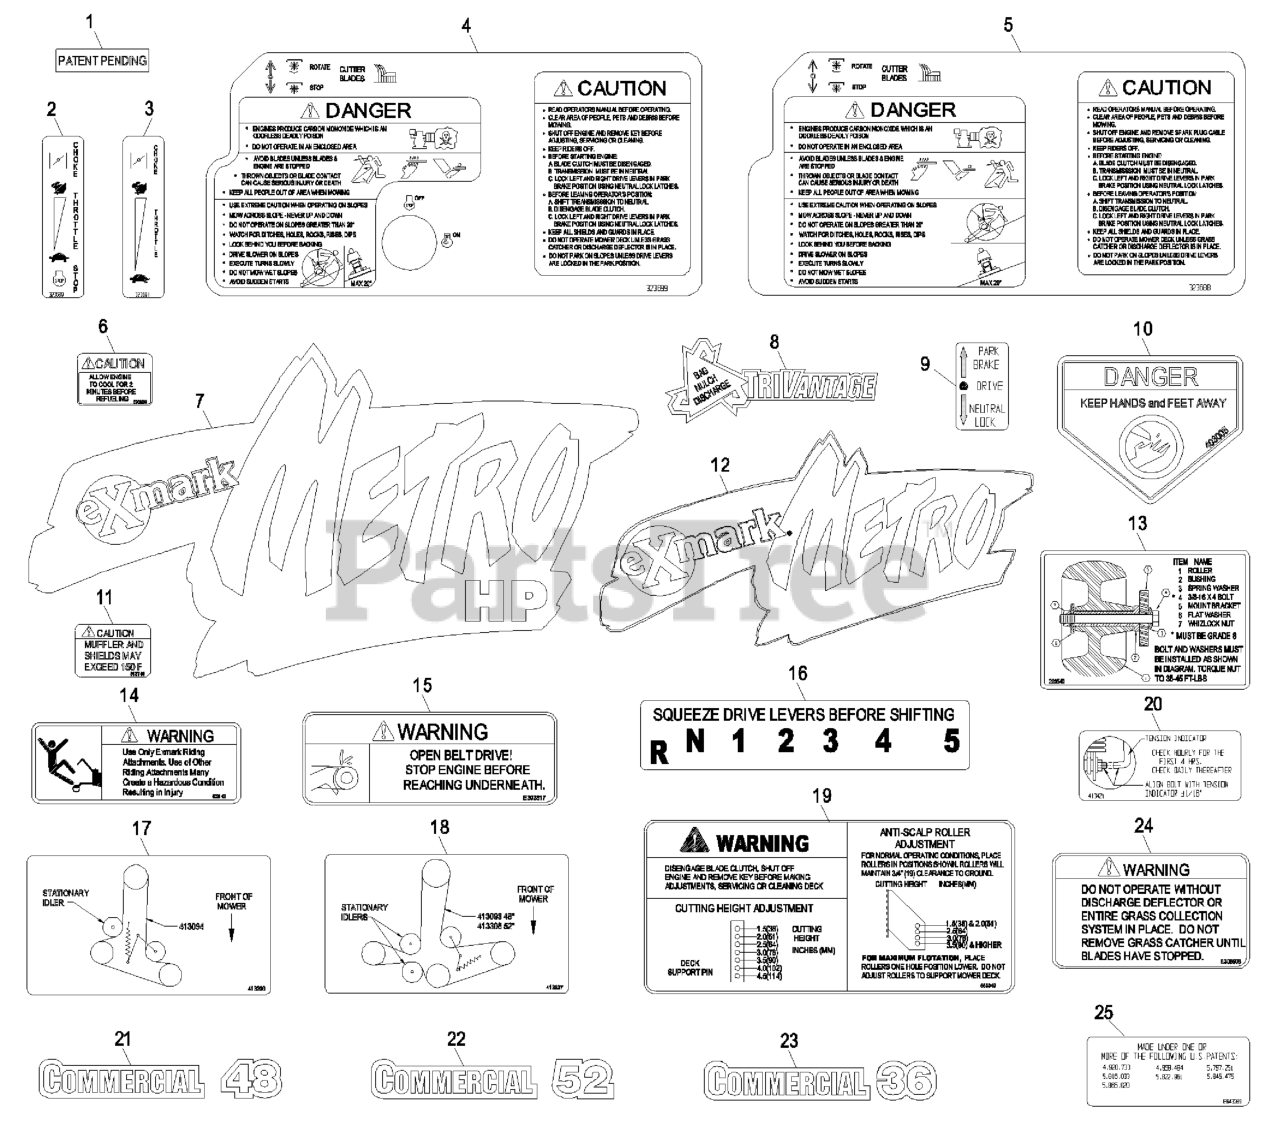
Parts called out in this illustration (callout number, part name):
1	Decal, Patent Pending
3	DECAL,THROTTLE
9	DECAL,NEUTRAL/BRAKE
10	DECAL-DANGER
13	DECAL,ROLLER MOUNTING
14	DECAL,SULKY WARNING
15	DECAL,BELT DRIVE
16	DECAL,SHIFTER
17	DECAL,BELT ROUTING
18	DECAL,BELT ROUTING
19	DECAL,ANTI SCALP
20	DECAL,INDICATOR
21	DECAL,COMMERCIAL 48
22	DECAL,COMMERCIAL 52
23	DECAL,COMMERCIAL 36
24	DECAL-WARNING, DISCHARGE
